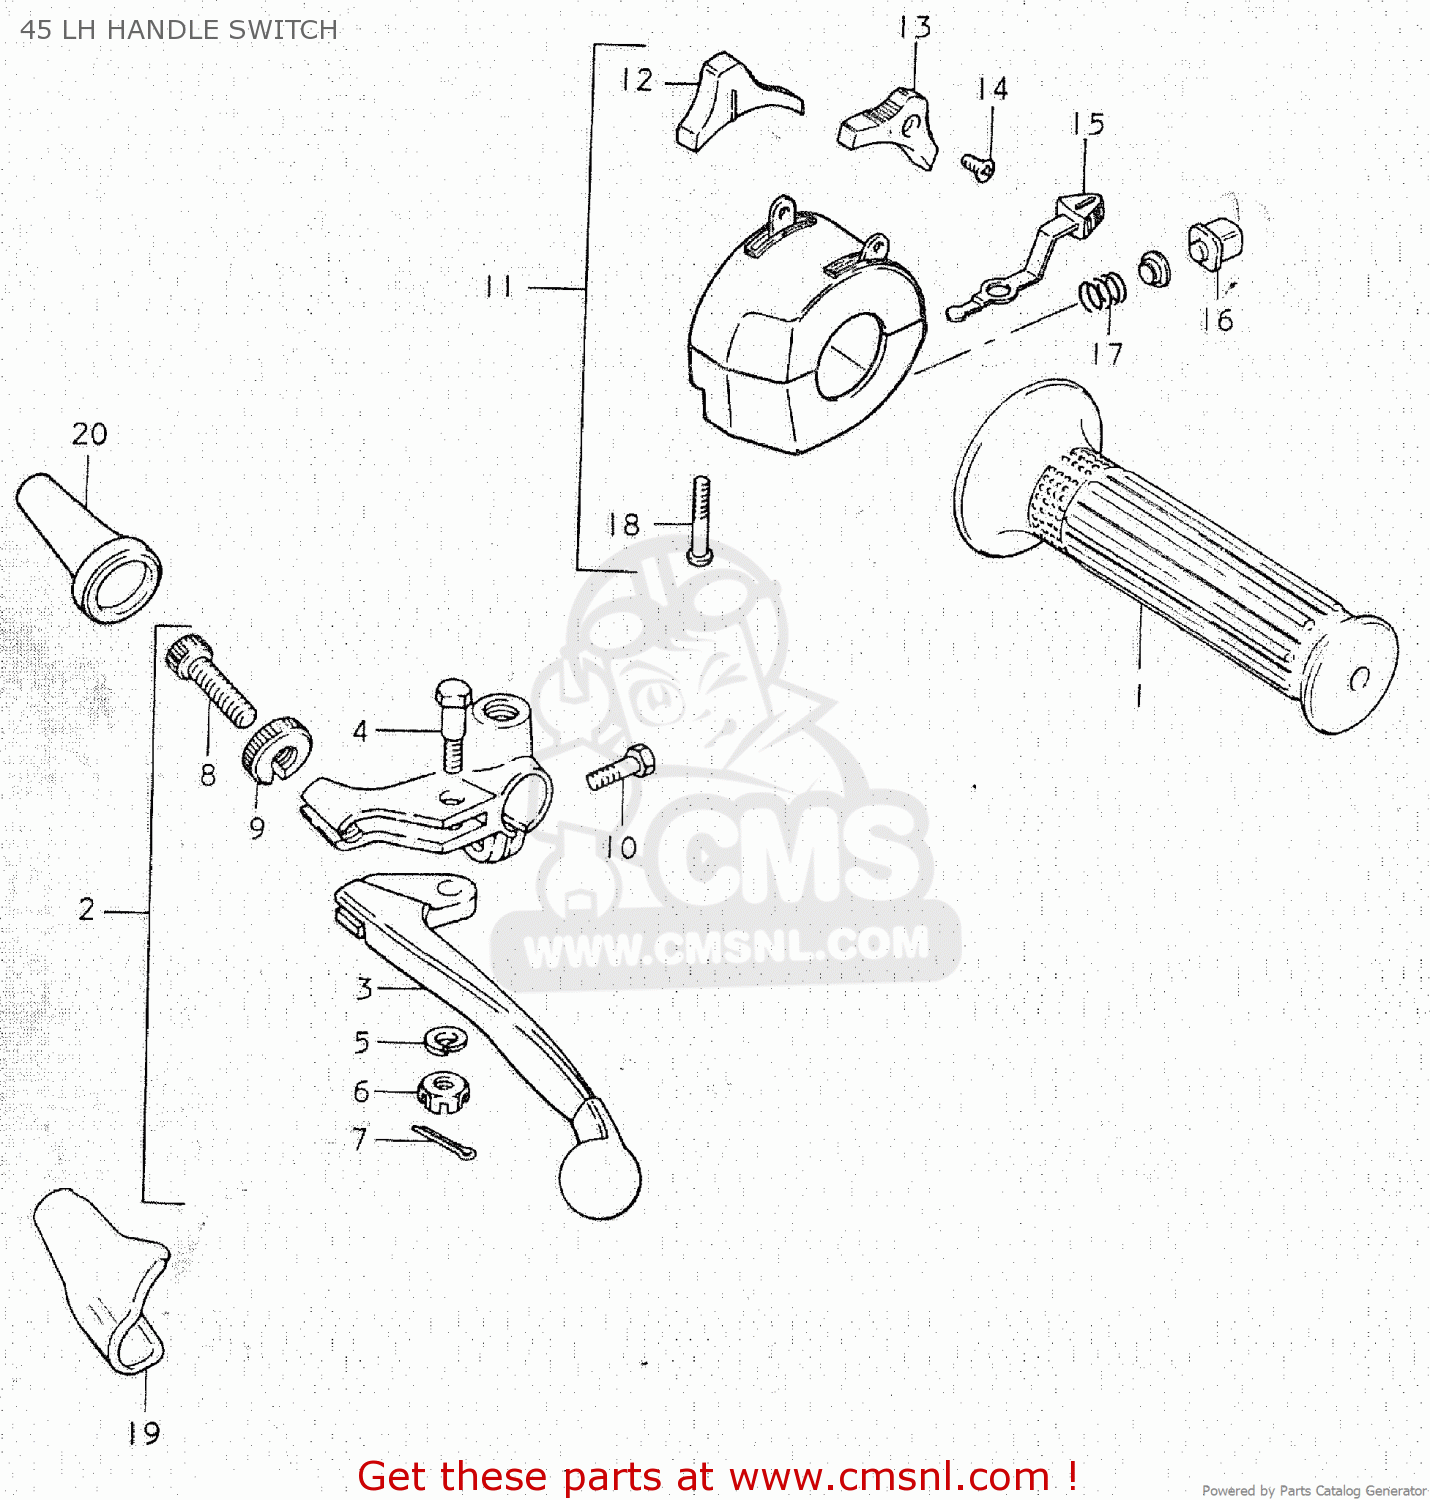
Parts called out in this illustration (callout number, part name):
1	GRIP,L
2	LEVER ASSEMBLY
3	LEVER,CLUTCH
4	BOLT,LEVER
5	LOCK WASHER
6	NUT,LEVER FITTNG
7	COTTER PIN
8	ADJUSTER,CABLE
9	NUT,CABLE ADJUSTER
10	BOLT
11	SWITCH ASSY,HANDLE LH
12	KNOB,LIGHTING SWITCH
13	KNOB,DIMMER SWITCH
14	SCREW
15	KNOB,TURNSIGNAL
16	BUTTON,HORN
17	SPRING
18	SCREW
19	COVER,CLUTCH LEVER
20	BOOT,CLUTCH CABLE
